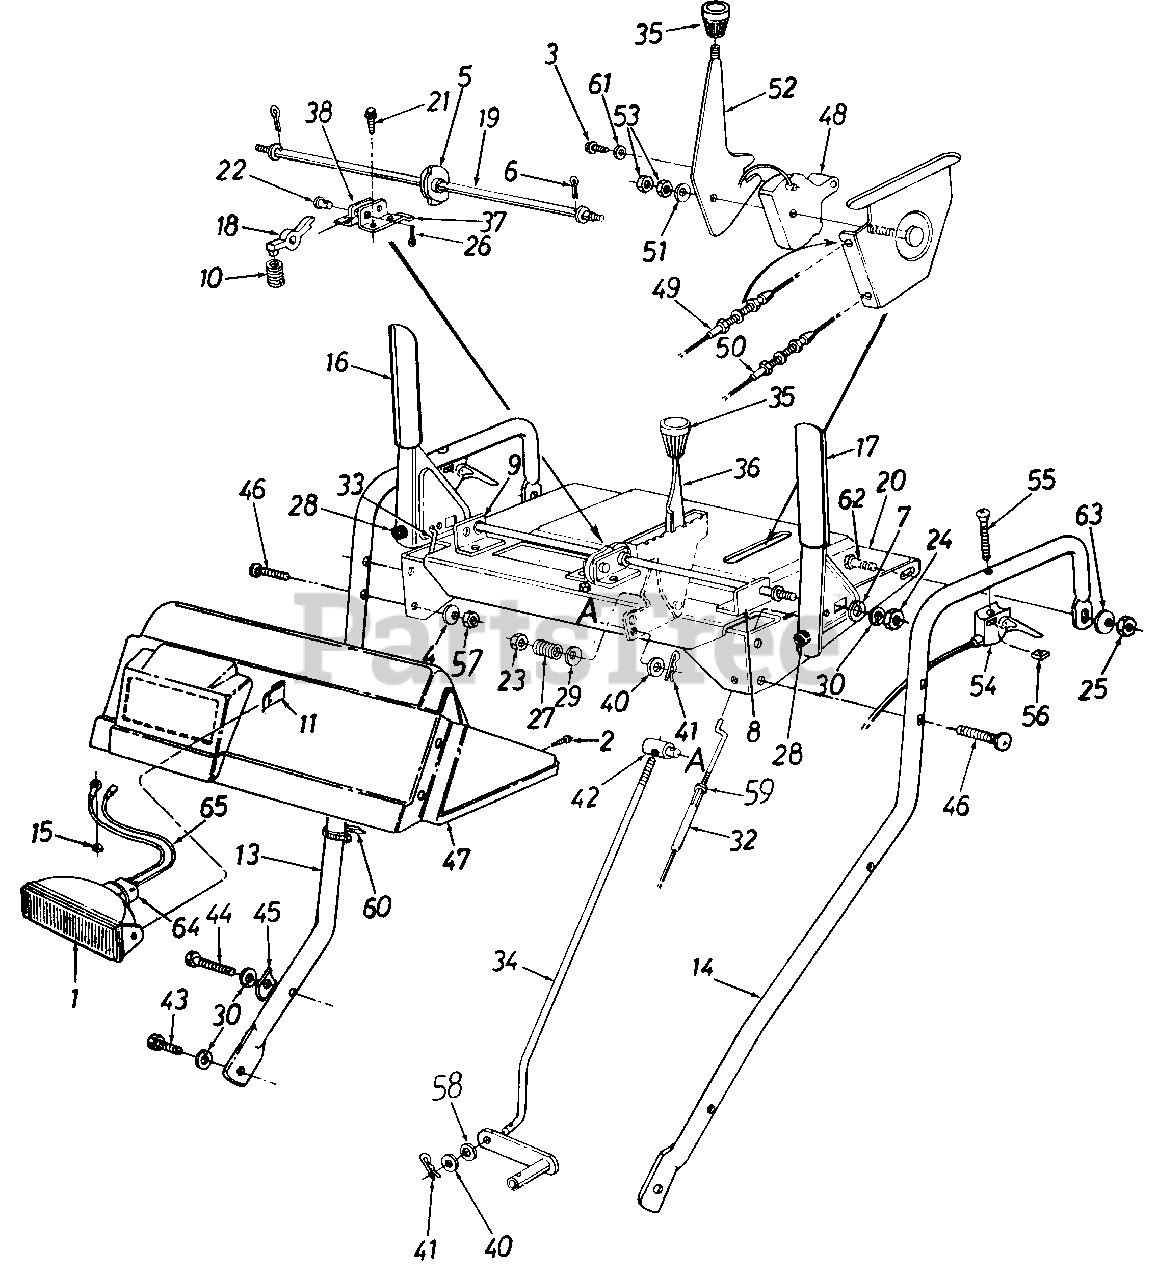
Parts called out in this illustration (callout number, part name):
1	Lamp Housing w/Lens (826T)
2	Truss Mach. B-Tap Scr. #10 x .5
3	Hex AB-Tap Scr. 1/4 x .62" Lg.
4	Bell-Wash. .325" I.D. x .88" O.D.
5	Cam Handle Lock
6	Cotter Pin 3/32" Dia. x .75" Lg.
7	Washer (Special) .72" O.D.
10	Compression Spring
11	Retaining Clip (826T)
13	Handle--R.H.
16	Engagement Handle--R.H.
17	Engagement Handle--L.H.
18	Pawl Handle Lock
22	Clevis Pin .437" Dia. x .65" Lg.
23	Hex Ins. L-Nut 3/8-24 Thd.
24	Hex Nut 5/16-18 Thd.
25	Hex Nut 1/4-20 Thd.
26	Cotter Pin 3/32" Dia. x 1" Lg.
27	Compression Spring
28	Rubber Bumper
29	Bell-Wash. .38" I.D. x .88" O.D.
30	L-Wash. 5/16" I.D.
32	Auger Clutch Cable
33	Drive Clutch Cable
34	Shift Rod
35	Shift Knob
36	Shift Handle
40	Fl-Wash. .344" I.D. x .62" O.D.
41	Internal Cotter Pin 5/16" Dia.
42	Ferrule
43	Hex Bolt 5/16-18 x .62" Lg.
44	Hex Bolt 5/16-18 x 1 75" Lg (Gr. 5)
45	Handle Tab
46	Curved Carr. Bolt 5/16-18 x 1.5" Lg.
48	Cable Guide
49	Chute Control Cable
50	Chute Control Cable w/Clip
51	Bell-Wash. .325" I.D. x .93" O.D.
53	Hex Cent. L-Nut 5/16-18 Thd.
54	Track Steer Cable w/Trigger
55	Oval C-Sunk Hd. Scr. 10-24 x 1.375" Lg.
56	Flat Weld Nut #10-24 Thd.
57	Hex Nut 5/16-18 Thd.
58	Spr. Wash. .32" I.D. x .62" O.D.
59	Hex Nut #10-24 Thd.
60	Cable Tie
61	Washer (Special) 1.25" O.D.
62	Hex Bolt 1/4-20 x .85" Lg.
63	Bell-Wash. .265" I.D. x .75" O.D.
64	Bulb (826T)
65	Wire Harness (826T)
